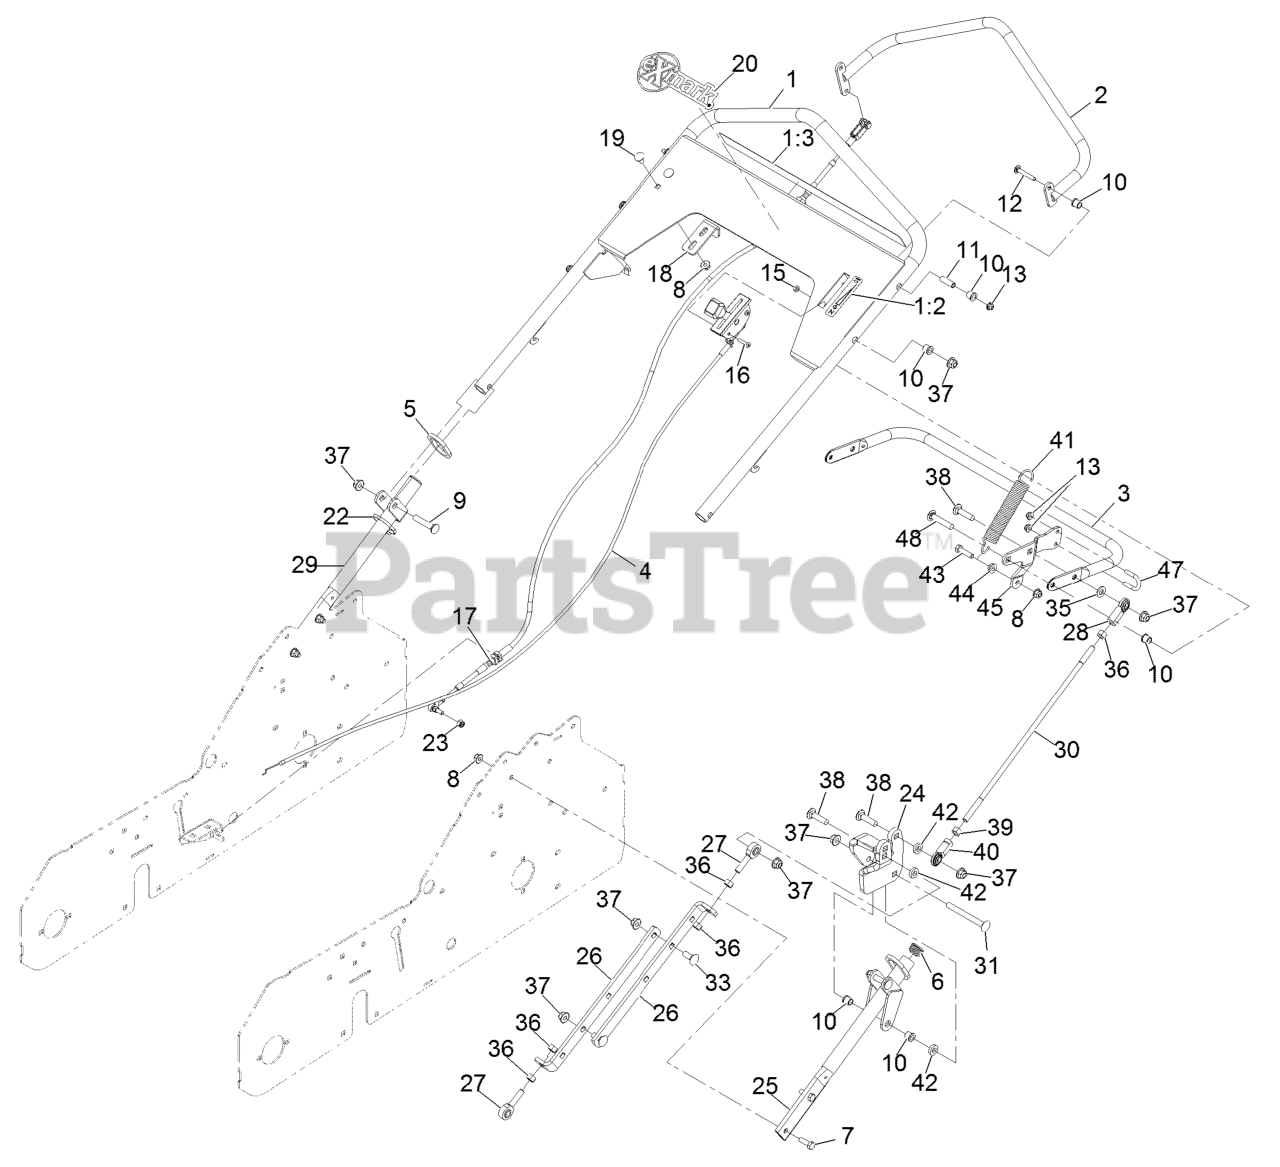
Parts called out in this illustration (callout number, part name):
1	HANDLE ASM
1:2	DECAL-THROTTLE, CHOKE
1:3	DECAL-AERATOR CONTROL PAN
2	TUBE-CONTROL
3	TUBE-HANDLE LIFT
4	CONTROL-THROTTLE
5	RING-HANDLE LOCK
7	SCREW-HH
8	NUT-HF, NI
9	SCREW-HH
10	BEARING
11	BUSHING-PIVOT
12	SCREW-CARR
15	NUT-LOCK, NI
16	SCREW-PPH
18	ANGLE-STOP
19	SCREW-CARR
20	DECAL,EXMARK LOGO
22	TIE-CABLE
23	NUT-LOCK
24	BRACKET-TRUNNION
25	HANDLE-LOWER, LH
26	LINK-LIFT
27	BALLJOINT
28	JOINT-BALL, END
29	HANDLE-LOWER
30	ROD-UPPER LINK
31	SCREW-CARR
33	BOLT-CARR
35	WASHER-FLAT
36	NUT-HEX
37	NUT-HF, NI
38	SCREW-CARR
39	NUT-HEX, LH
40	JOINT-BALL END, LH
41	SPRING-EXTENSION
43	SCREW-HH
45	BRACKET-SPRING
48	BOLT-CARRIAGE
